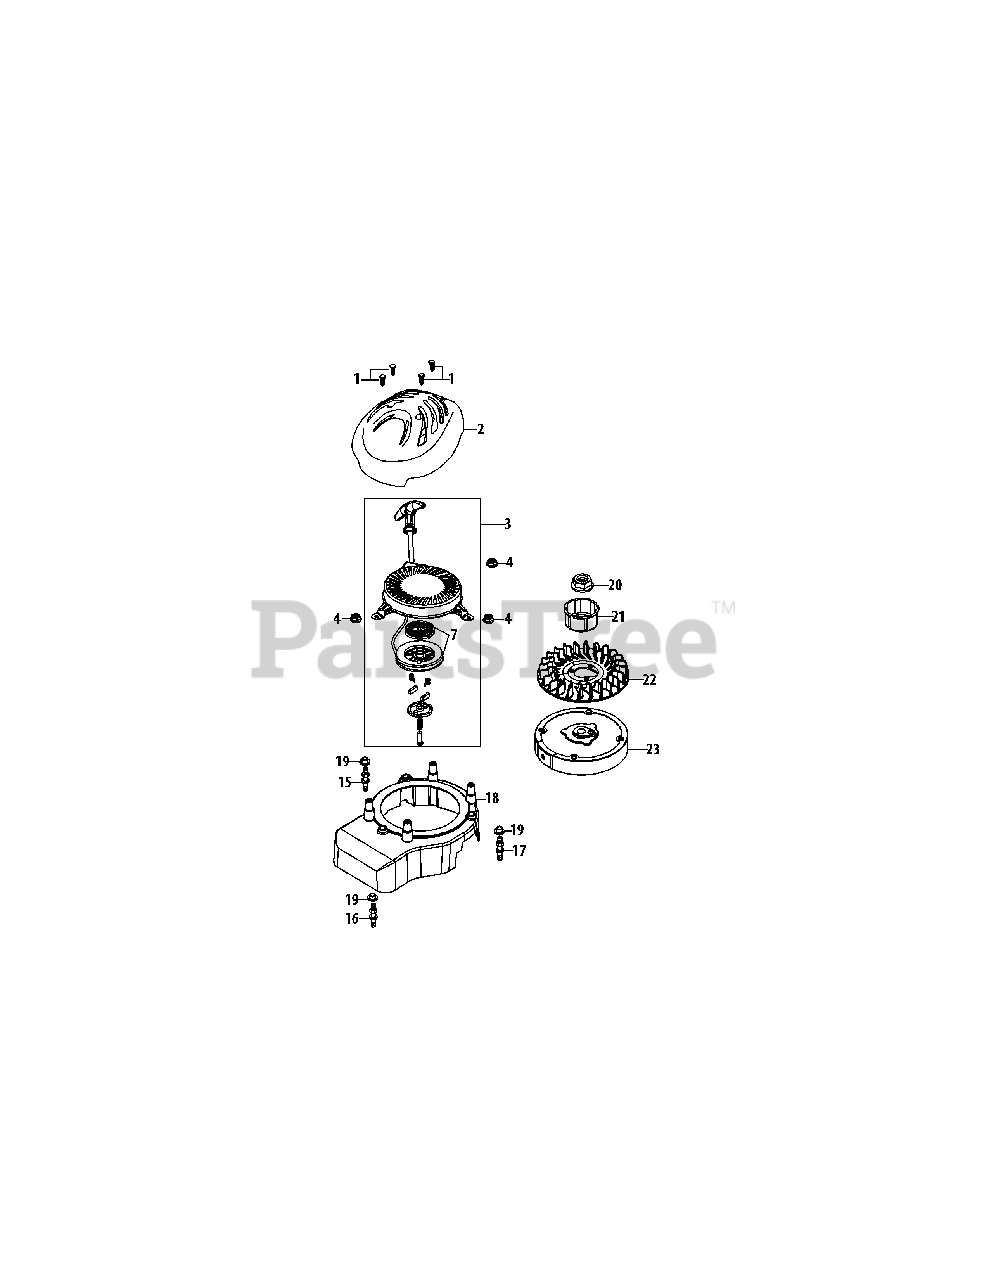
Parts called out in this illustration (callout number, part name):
1	Self-Tapping Bolt, #12-16 X 1.00"
2	Outer Shroud (Application Specific)
3	Recoil Starter Assembly
4	Nut M6X10Mm Starter/Carb/Muff
7	Recoil Spring And Pulley Assy
15	Shroud Stud Left/Black/Wh Zinc
16	Shroud Stud Front/Unmarked/Wh Zinc
17	Shroud Stud Right/White/Wh Zinc
18	Inner Shroud
20	Flywheel Nut M14
21	Starter Cup
22	Cooling Fan
